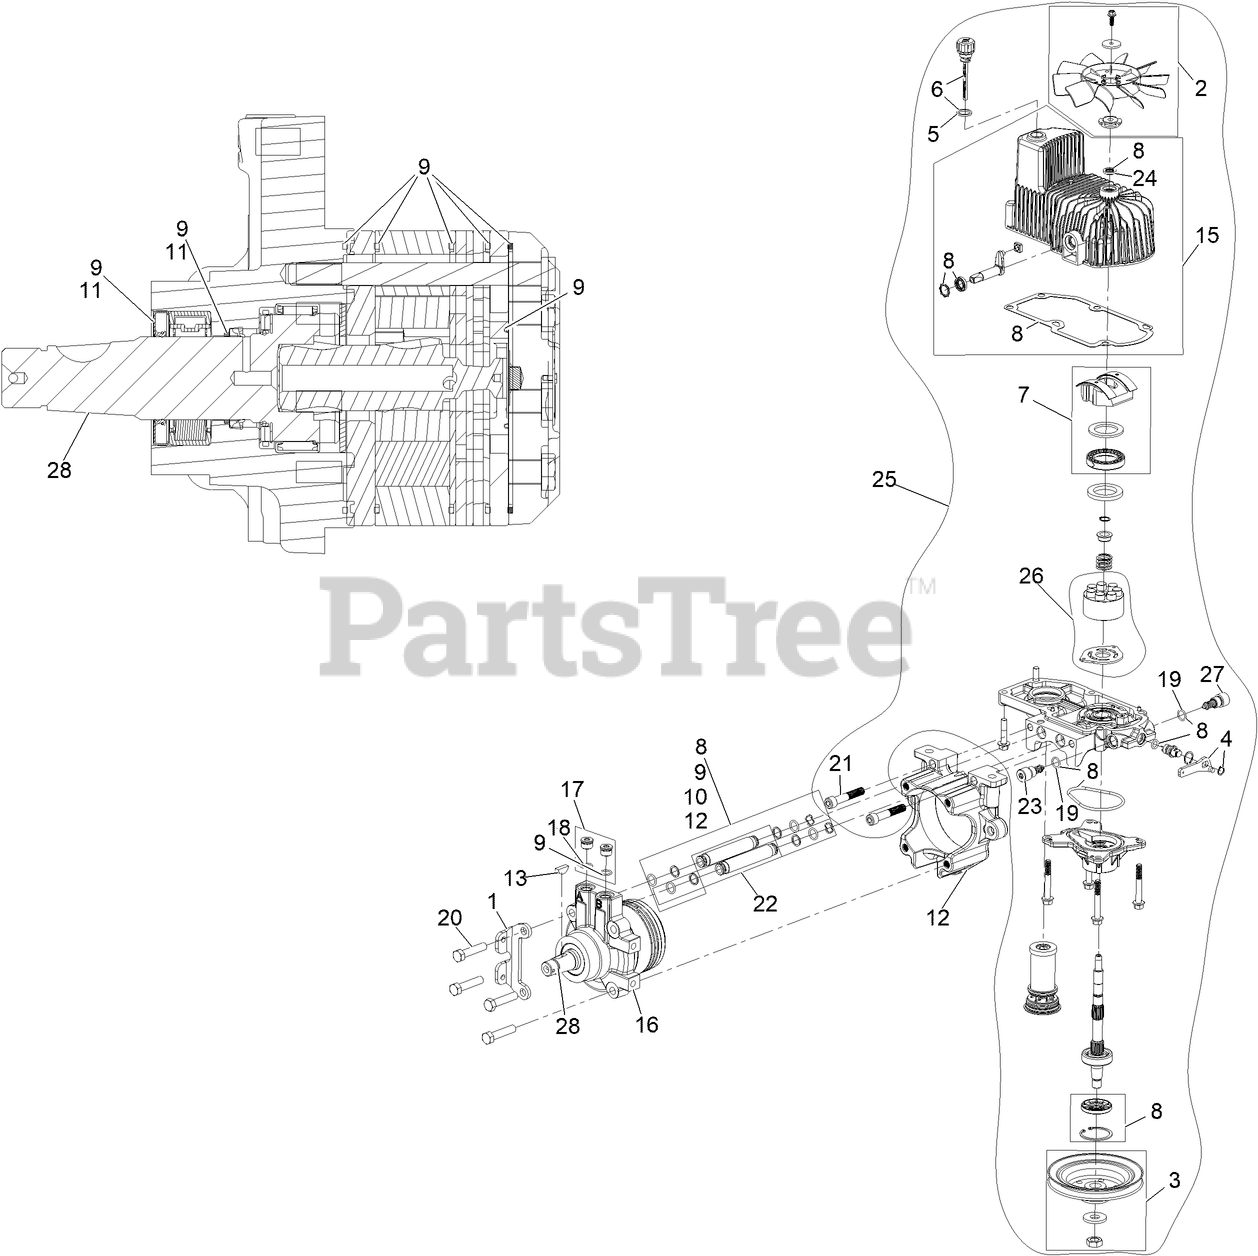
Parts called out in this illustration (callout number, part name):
1	PLATE, HORSE SHOE MOUNT
2	KIT, 7.8 IN FAN
3	PULLEY KIT
4	HANDLE-BYPASS VALVE, HYDRO
5	DIPSTICK-HYDRO W/GASKET
6	GASKET-DIPSTICK, HYDRO
7	SWASH BLOCK KIT
8	KIT, PUMP SEAL
9	MOTOR SEAL KIT
10	TUBE SEAL KIT
11	OUTPUT SHAFT SEAL KIT
12	NOSE CUP-UHT
13	KEY-WOODRUFF
15	KIT, HOUSING-HYDRO RH
16	KIT, MOTOR TG310CC RH
17	MAGNETIC PLUGS SERVICE KIT
18	O-RING
19	O-RING-CHECK VALVE
20	SCREW HH
21	SCREW-HSH
22	HYDRAULIC TUBE KIT
23	SHOCK VALVE, 12CC HYDRO
24	SEAL-FAN DRIVE
25	KIT, PUMP SECTION 16CC RH
26	KIT - 16CC PORT PLATE,ROTATE GRP
27	SHOCK VALVE ORIFICED 3800
28	SHAFT-COUPLING
